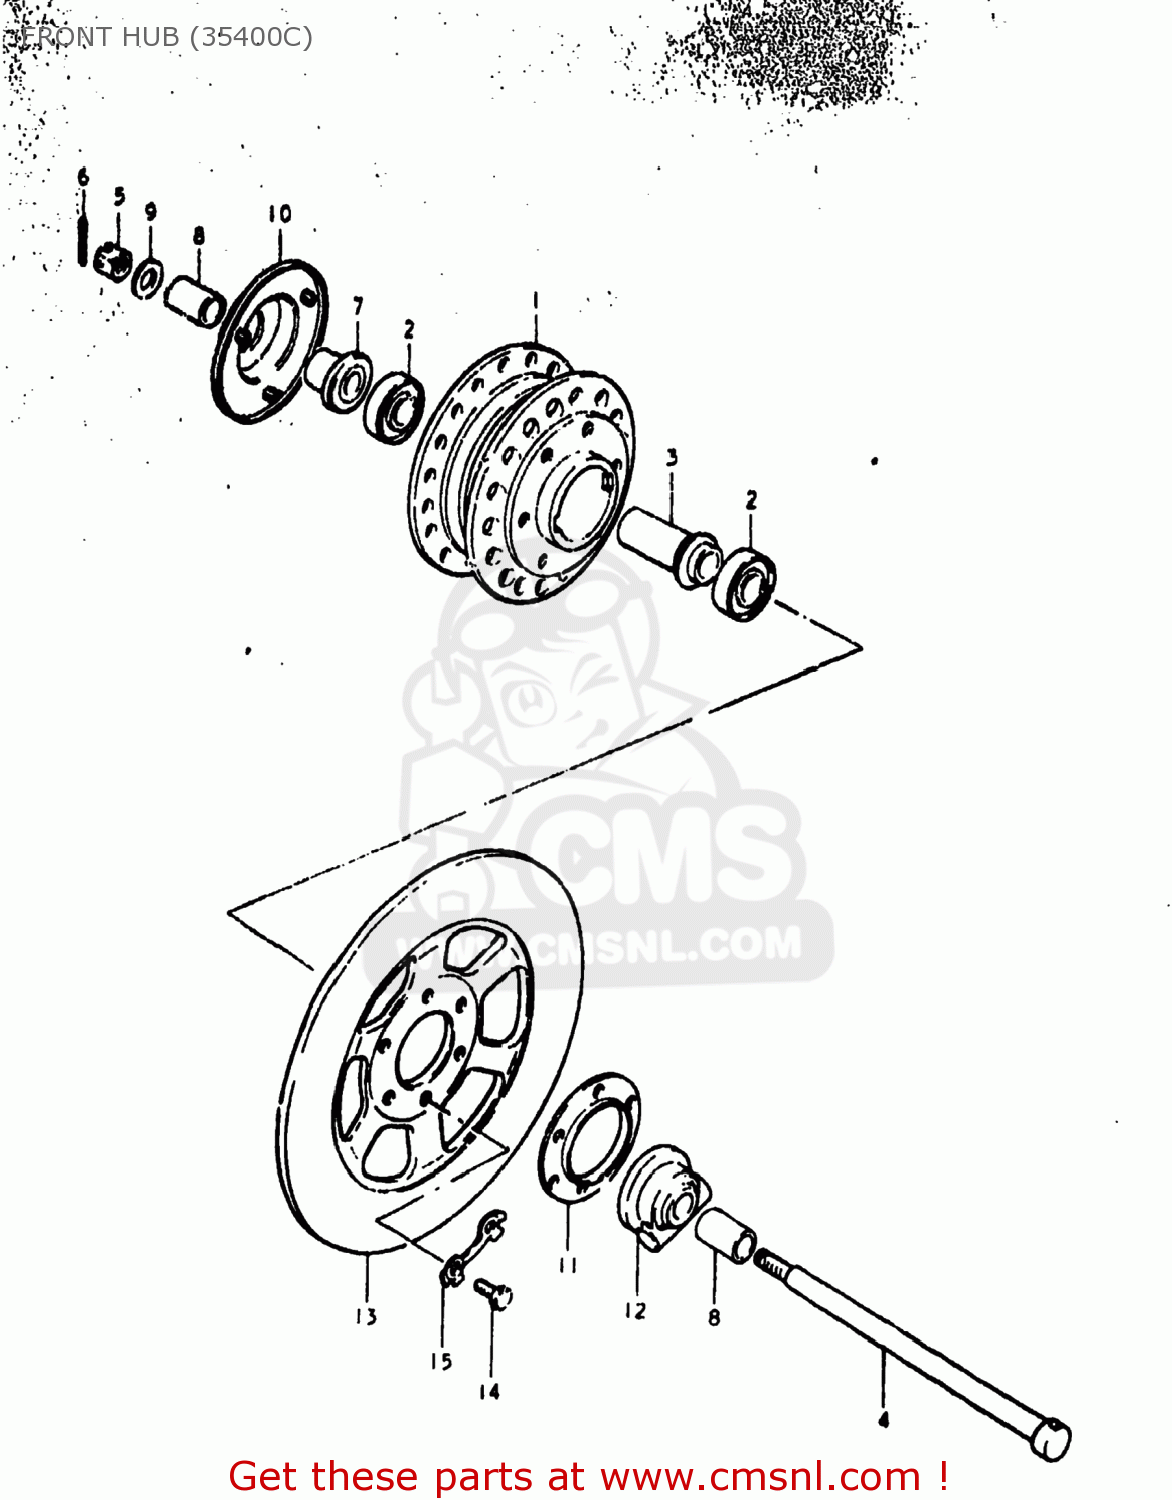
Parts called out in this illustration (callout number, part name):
1	HUB,FRONT WHEEL
2	BEARING
3	SPACER,FR HUB BEARING
4	AXLE,FRONT
5	NUT 12MM
6	COTTER PIN
7	SPACER,FRONT AXLE,RIGHT
8	SPACER(15X22X30)
9	WASHER
10	COVER,FR HUB,R
11	DUST SEAL,SPEEDOMETER GEAR BOX
12	BOX ASSY,SPEEDOMETER GEAR
13	DISC,REAR BRAKE
14	BOLT(8X25)
15	WASHER
